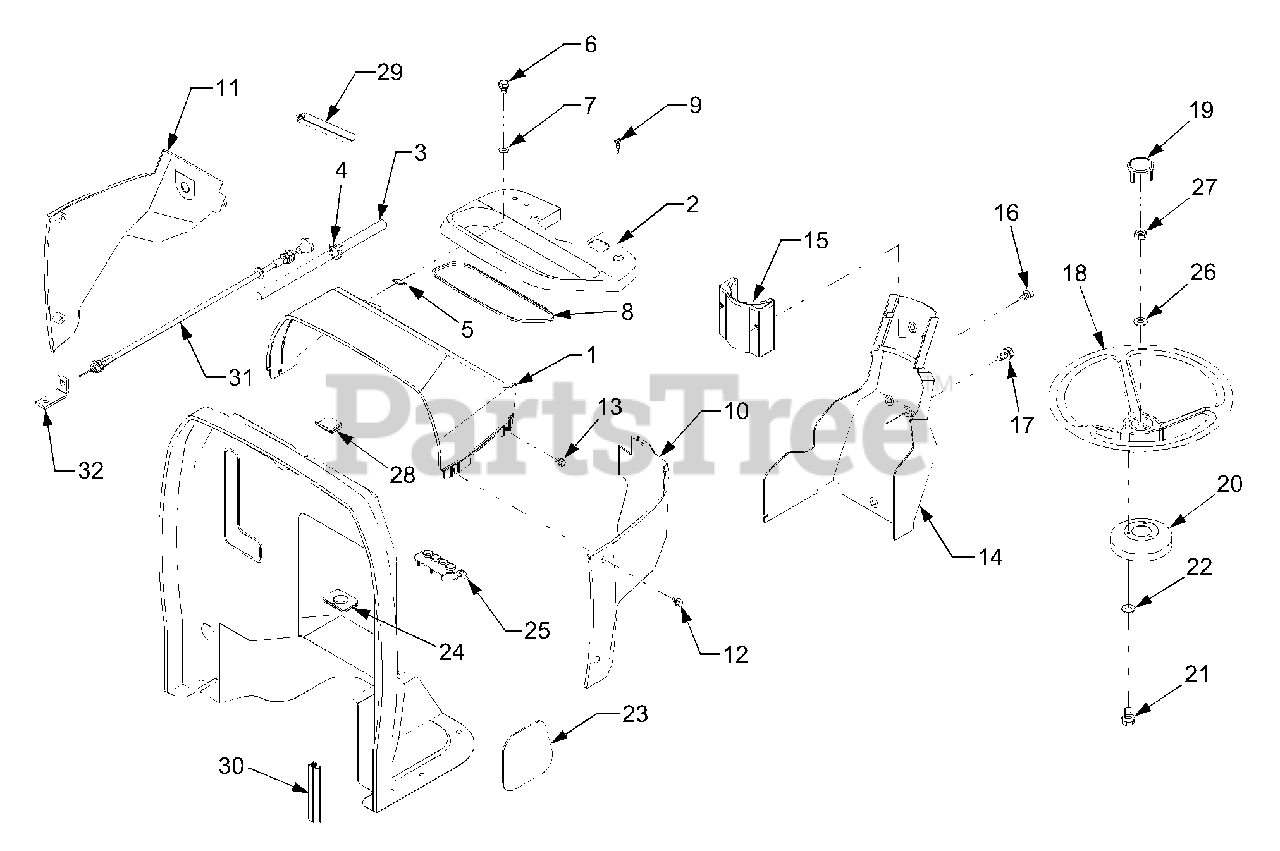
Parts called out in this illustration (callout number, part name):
1	Hood, Instrument
2	Cover, Instrument
7	Washer, Plain
10	Cover, Instrument (LH)
11	Cover, Instrument (RH)
14	Cover 1, Steering
15	Cover 2, Steering
18	Steering Wheel
19	Cap, Steering Wheel
20	Cover, Steering Wheel
22	Washer, Plain
26	Washer, Spring
31	Wire, Engine Stop
